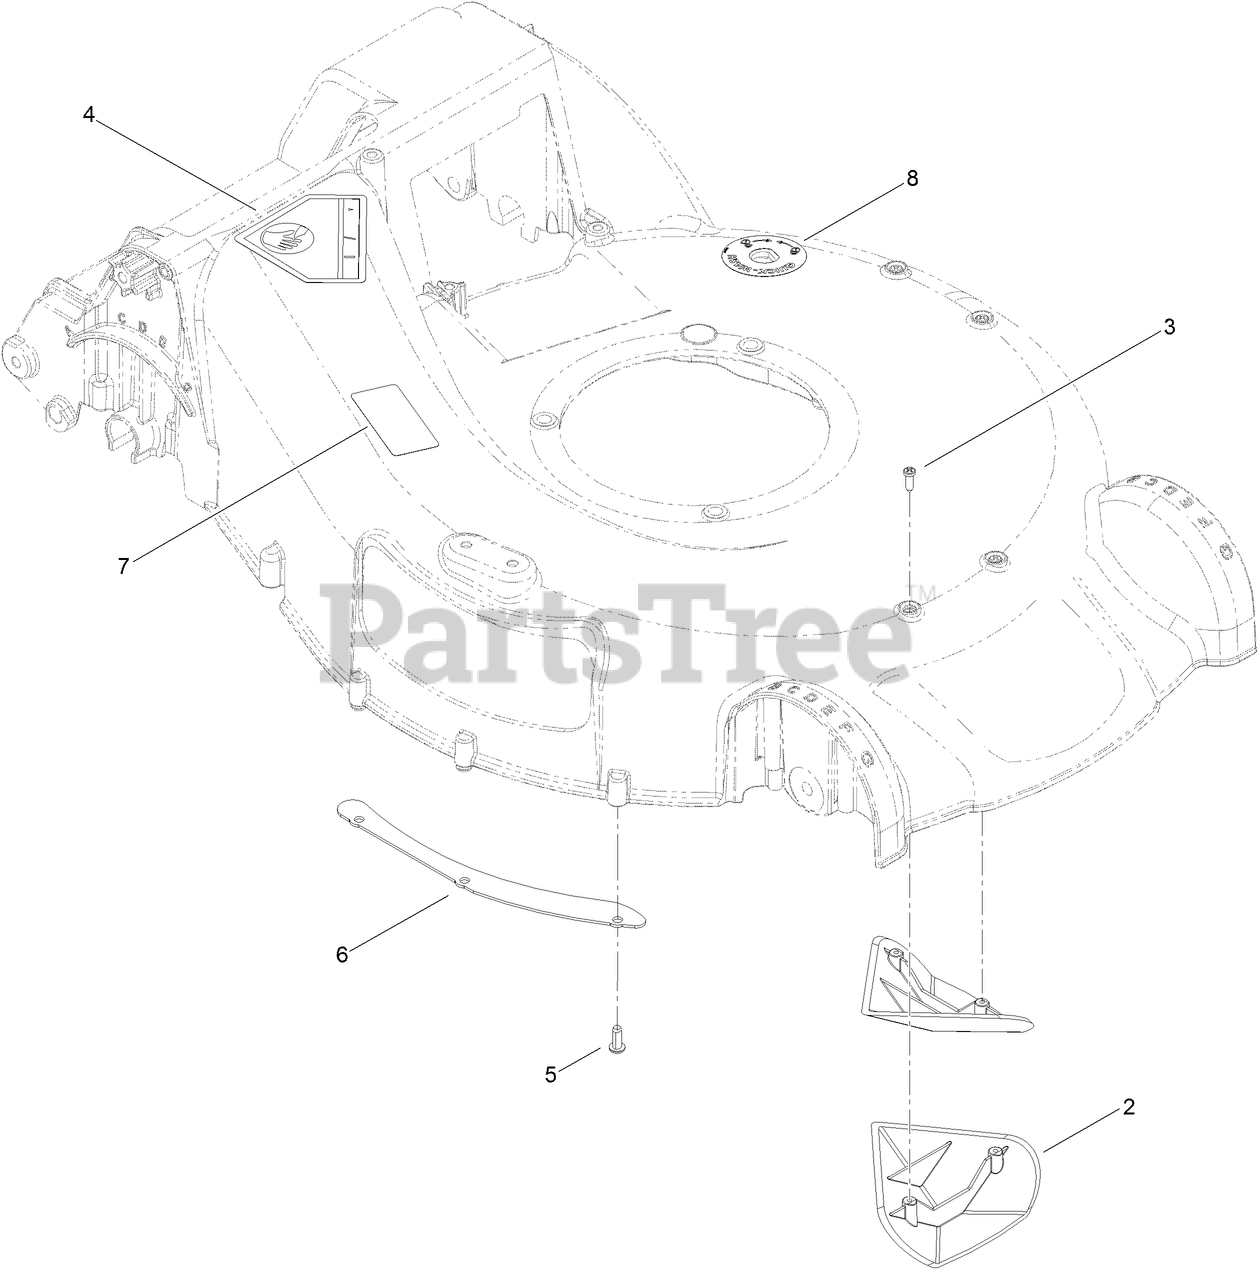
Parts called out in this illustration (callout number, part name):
2	KICKER-HOUSING
3	SCREW-PPH
4	DECAL-DANGER
5	SCREW
6	SHEET-LIP
7	DECAL-PLACEMENT, FOOT
8	DECAL-PORT, WASHOUT
